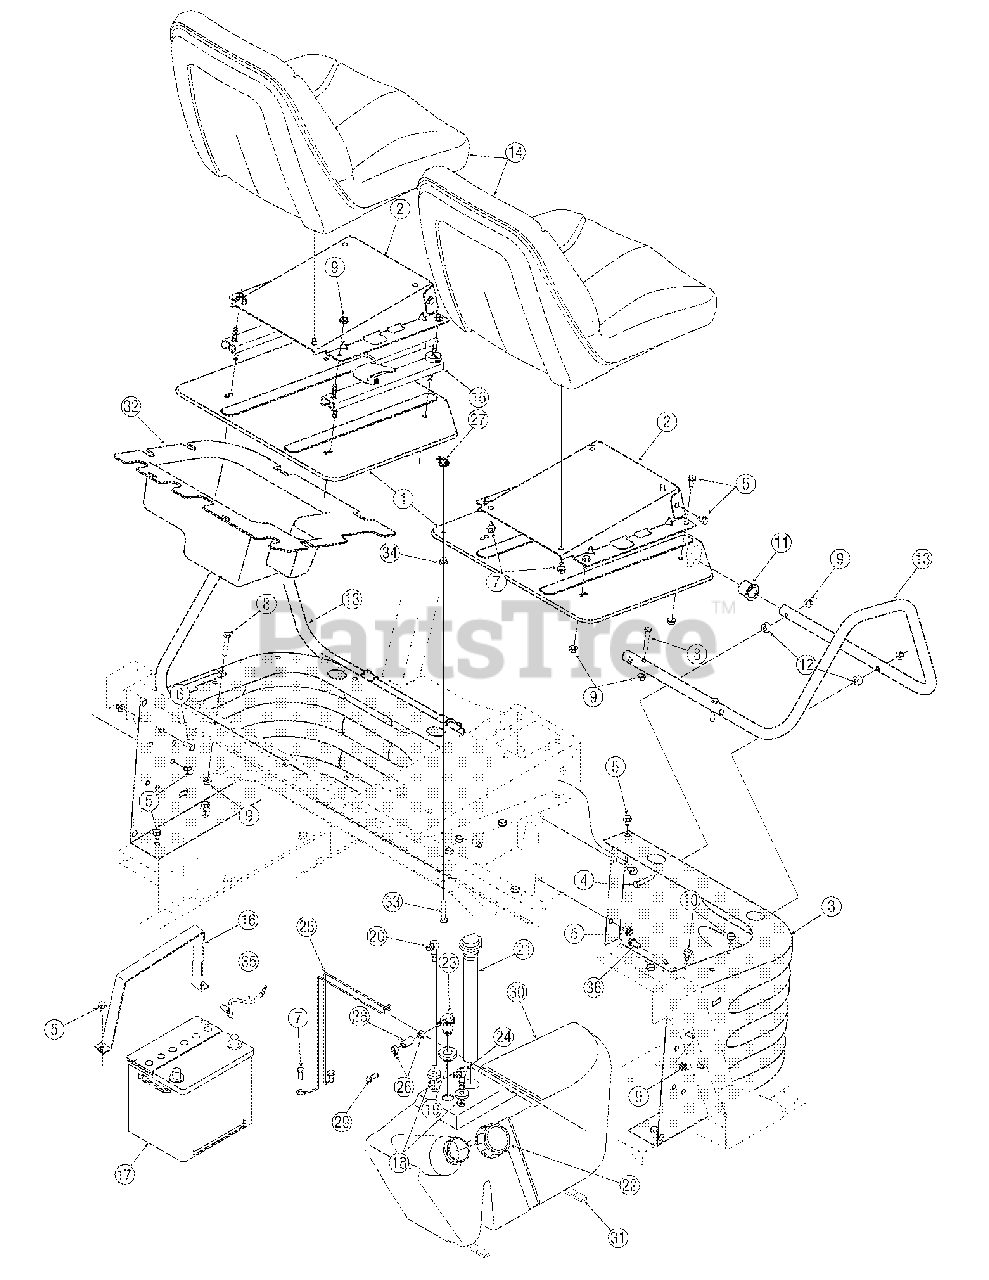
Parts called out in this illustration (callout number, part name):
5	Scr., TT, 5/16-18 x .500
6	Screw, LD, 5/16-18 x .750
7	Screw, 5/16-18 x .500
8	Screw, 5/16-18 x 1.75
9	Nut, Flglk, 5/16-18
10	Bmpr, .62 Dia. x .3
11	Brg, Flg, .894 ID x 1.1315
12	Spcr, .315 x .750 x .375
14	Seat
15	Track, Seat
17	Battery, 540 CCA Dry
18	Bush, Tank, Gas
19	Bush, Tank, Vent
20	Ftg, Fuel, Pickup, 4x4
21	Sensor, Fuel, Low
22	Cap, Fuel Kohler Engine
22	Cap, Fuel Diesel Engine
23	Ftg, Fuel, Vent
24	Ftg, Fuel, Pickup Diesel Engine
25	Wire, tank, fuel
26	Clamp, Hose, .490 Dia.
27	Nut, Wing, 1/4-20
28	Fuel Line, 5/16 Id X .56 Kohler Engine
28	Hose, Fuel Line Diesel Engine
29	Vent, 3/8 Dia. Diesel Engine
30	Tank assembly, Fuel Kohler Engine
30	Tank assembly, Fuel Diesel Engine
31	Tape, .625 Wide X.25 Thk
32	Tray, Seat box
33	Screw, 1/4-20 x 1.00
34	Nut, Flange Lock, 1/4-20
35	Wire, Ground, Engine
36	Screw, Hex, 5/16-18 x .75
